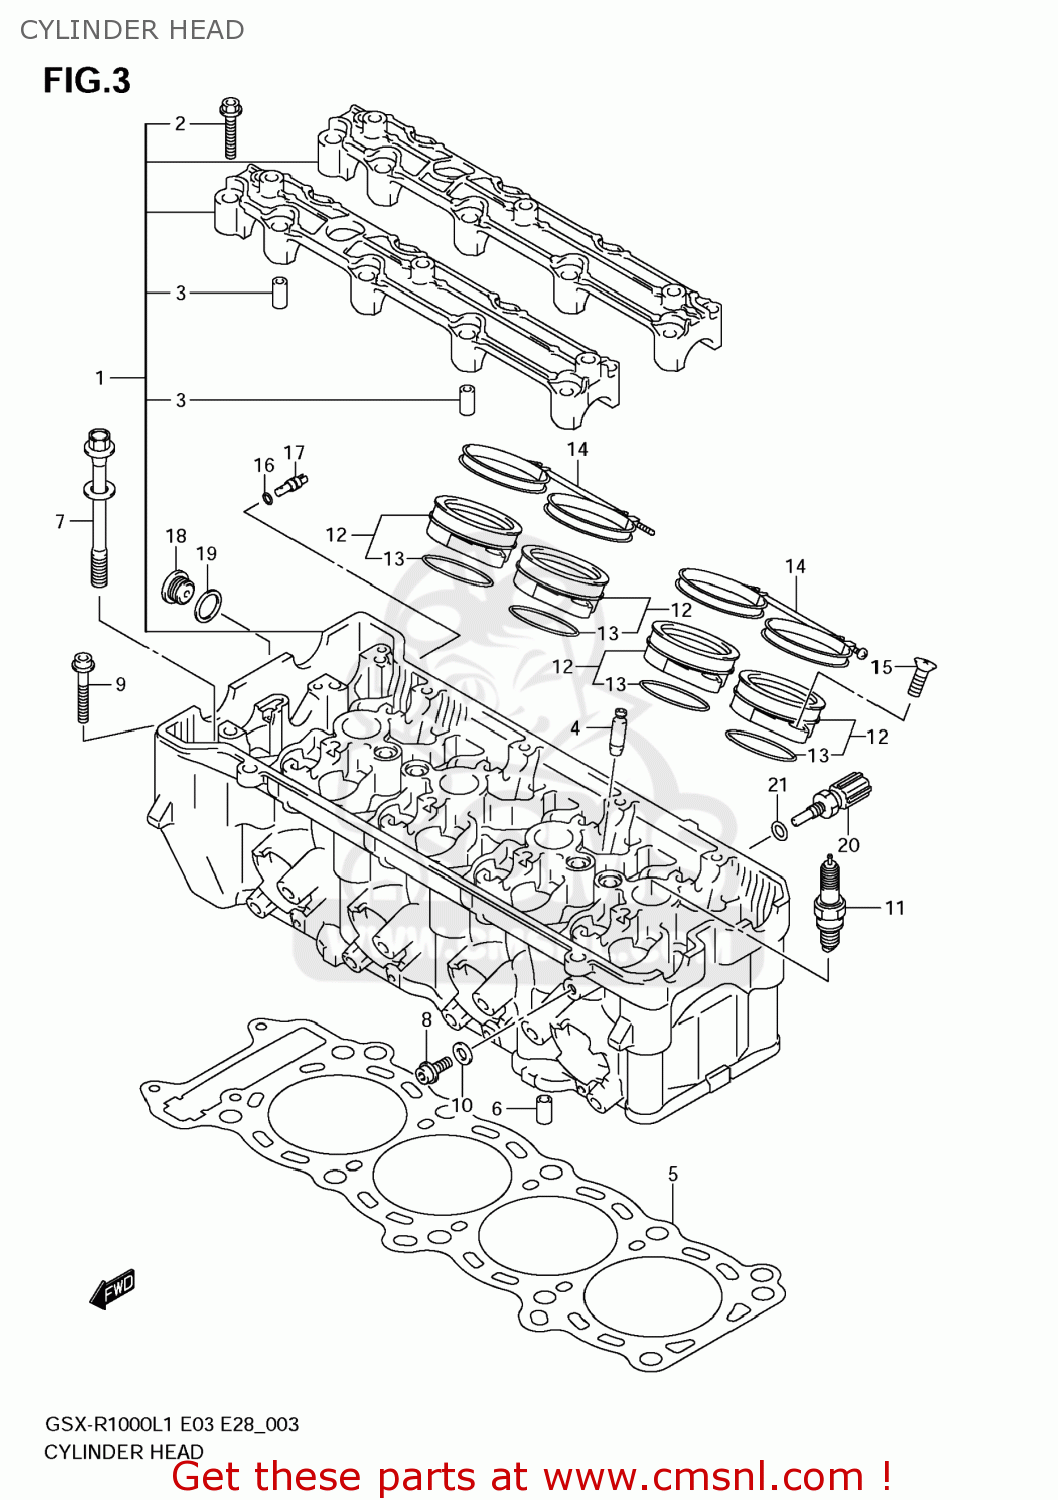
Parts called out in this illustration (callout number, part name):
1	HEAD ASSY,CYLINDER
2	BOLT(6X40)
3	PIN(6.2X8X16)
4	GUIDE,VALVE(OS:0.3)
5	GASKET,CYLINDER HEAD (NAS)
6	PIN
7	BOLT,CYLINDER HEAD(L:105)
8	BOLT(6X12)
9	BOLT
10	GASKET(5.8X13X1.2) (NAS)
11	PLUG,SPARK(IU27D)
12	PIPE ASSY,INTAKE
13	O RING(D:2.4,ID:47.2)
14	CLAMP,INTAKE PIPE
15	SCREW
16	O RING(D:1.2,ID:4)
17	JET,OIL GALLERY(16)
18	PLUG,16X8
19	GASKET(16X22X0.8) (NAS)
20	SENSOR,TEMP
21	GASKET(12X17X1) (NAS)
